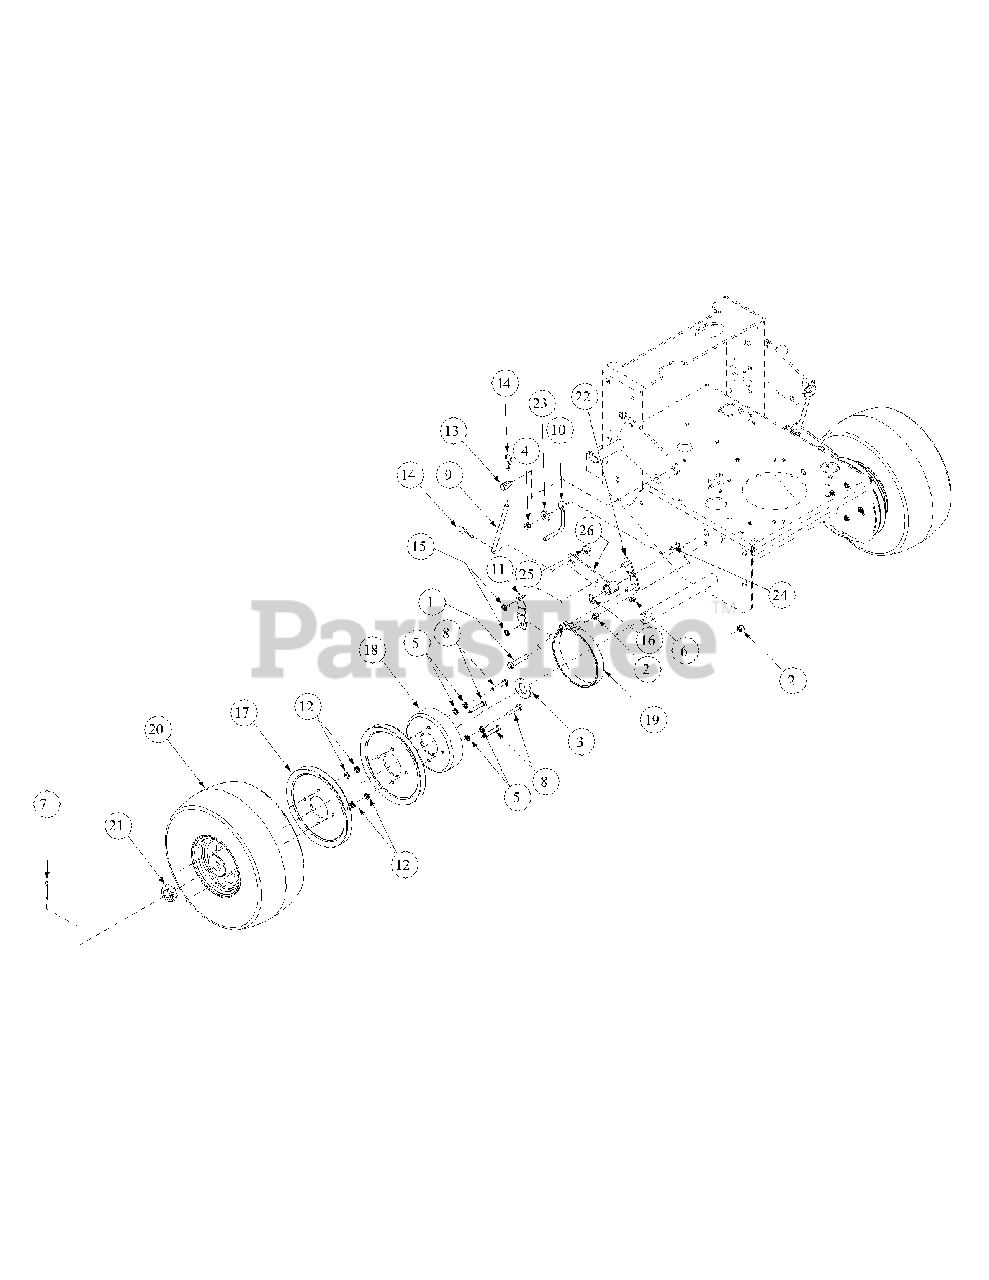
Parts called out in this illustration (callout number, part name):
1	Hex Cap Screw, 3/8-16 x 2.00
2	Hex Nut, 3/8-16
3	Flat Washer, 2.000 x 1.005
4	Nut, Nylock, 5/16-18
5	Lock Washer, 5/16 Zinc
6	Grease Fitting, 1/4-28, 90°
7	Cotter Pin, 5/32 x 1-1/2 Zinc
8	Hex Cap Screw, 5/16-18 x 1-1/2
9	Brake Rod
10	Drive Belt Guide
11	Brake, Bracket Link
12	Drive Wheel Pulley Spacer
13	Swivel Joint
14	Hair Pin, 3/8-1/2
15	Retainer, Push ON, 3/8
16	E-Ring, 5/8
17	Drive Pulley, V
18	Drum Brake
19	Band Brake
20	Wheel Assembly, 13 x 6.50-6
20	Tire, 13 x 6.50-6
21	Hex Jam Nut, 1-14
22	Brake Link
23	Idler Washer
24	Carriage Bolt, 5/16-18 x 1
25	Flat Washer, 5/16
26	Brake Lever Weldment
